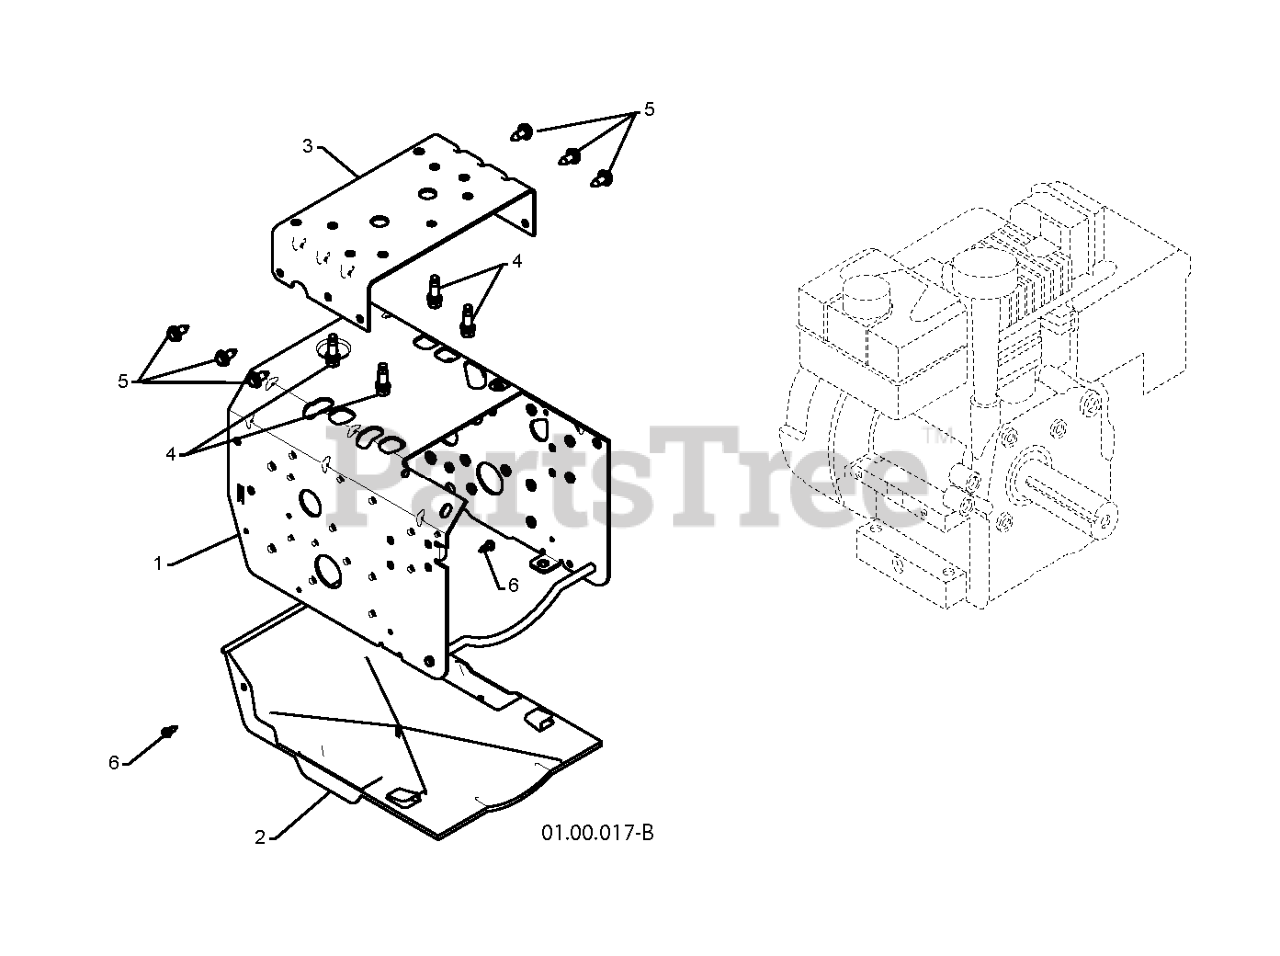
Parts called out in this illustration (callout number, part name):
1	FRAME.WELD.PNT.003BGP
2	PAN.BOTTOM.PLASTIC
3	PLATE.ENGINE.MOUNT.ORANGE
4	BOLT 3/8-16X1-1/8
5	BOLT.HEX.HD.WASHER.5/16-18X.75
6	SCREW, HEX HEAD, TAPPING
